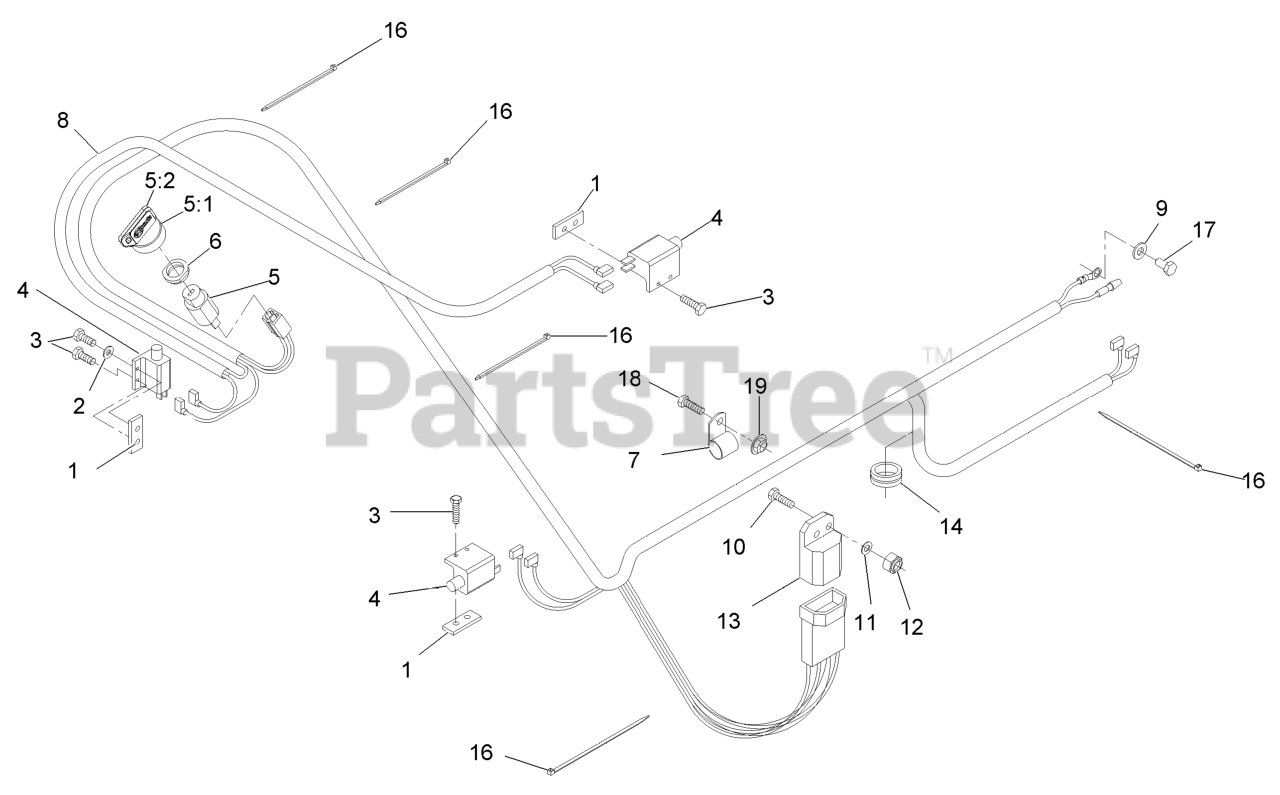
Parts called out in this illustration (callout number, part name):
1	PLATE-TAPPED
2	WASHER-FLAT
3	SCREW-PPH
4	SWITCH-OPEN, NORMALLY
5	SWITCH & KEY (INCLUDES NU
5:1	KEYS-IGNITION (SPARE PAIR
5:2	KEY-IGNITION
6	NUT-SWITCH, IGNITION
7	CLIP-LOOM
8	HARNESS-WIRING
9	WASHER-PLAIN
10	SCREW-HH
11	WASHER-FLAT
12	NUT-LOCK, NI
13	MODULE-INTERLOCK
14	GROMMET
16	TIE-CABLE
17	SCREW-HH
18	SCREW-HH
